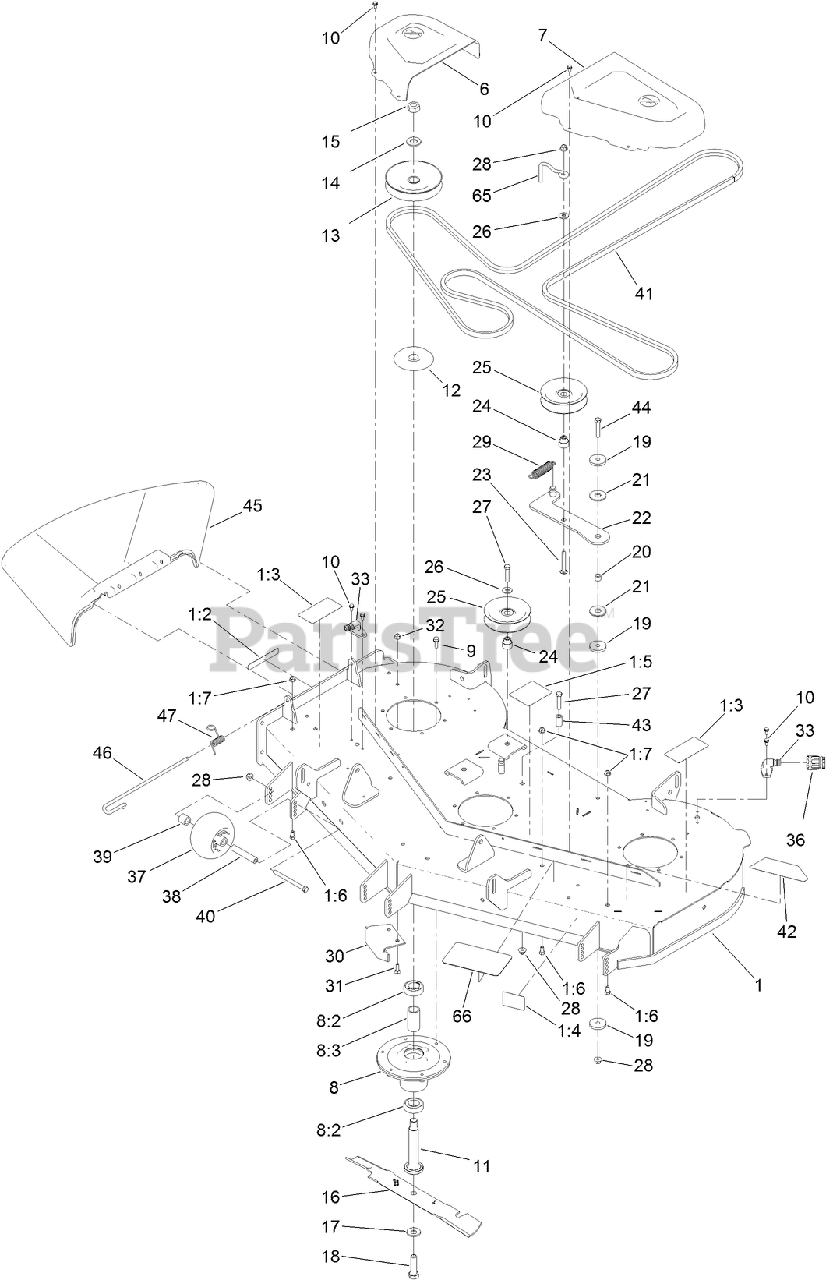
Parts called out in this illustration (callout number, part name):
1	DECK ASM
1:2	DECAL-DANGER
1:3	DECAL-DANGER, DECK
1:4	DECAL-SCALP, ANTI
1:5	DECAL-ROUTING, BELT
1:6	SCREW-HH
1:7	NUT-HF, NI
6	COVER-BELT, RH
7	COVER-BELT, LH
8	SPINDLE ASM
8:2	BEARING-BALL
8:3	SPACER-BEARING
9	SCREW-TAPTITE
10	SCREW-HWH
11	SHAFT-SPINDLE
12	SHIELD-BEARING
13	PULLEY
14	WASHER
15	NUT-HEX
16	BLADE-HI FLO
17	WASHER-BELLEVILLE
18	SCREW-BLADE
19	WASHER-PLAIN
20	BUSHING-LEVER, LIFT
21	WASHER-FRICTION, COMPOSITE
22	ARM-IDLER
23	SCREW-CARR
24	BUSHING-IDLER
25	PULLEY-IDLER, FLAT
26	WASHER-HARDENED
27	SCREW-HH
28	NUT-HF, NI
29	SPRING-EXTENSION
30	BAFFLE-CUTOFF
31	SCREW-CARR
32	NUT-HF, NI
33	FITTING-WASHOUT
36	CONNECTOR-HOSE
37	ROLLER-SCALP, ANTI
38	TUBE-SPANNER
39	SPACER-AXLE, REAR
40	SCREW-HH
41	V-BELT
43	SPACER
44	SCREW-HH
45	DEFLECTOR-DISCHARGE
46	PIN-CHUTE
47	SPRING-TORSION
65	GUIDE-BELT, IDLER
66	TREAD-STEP
